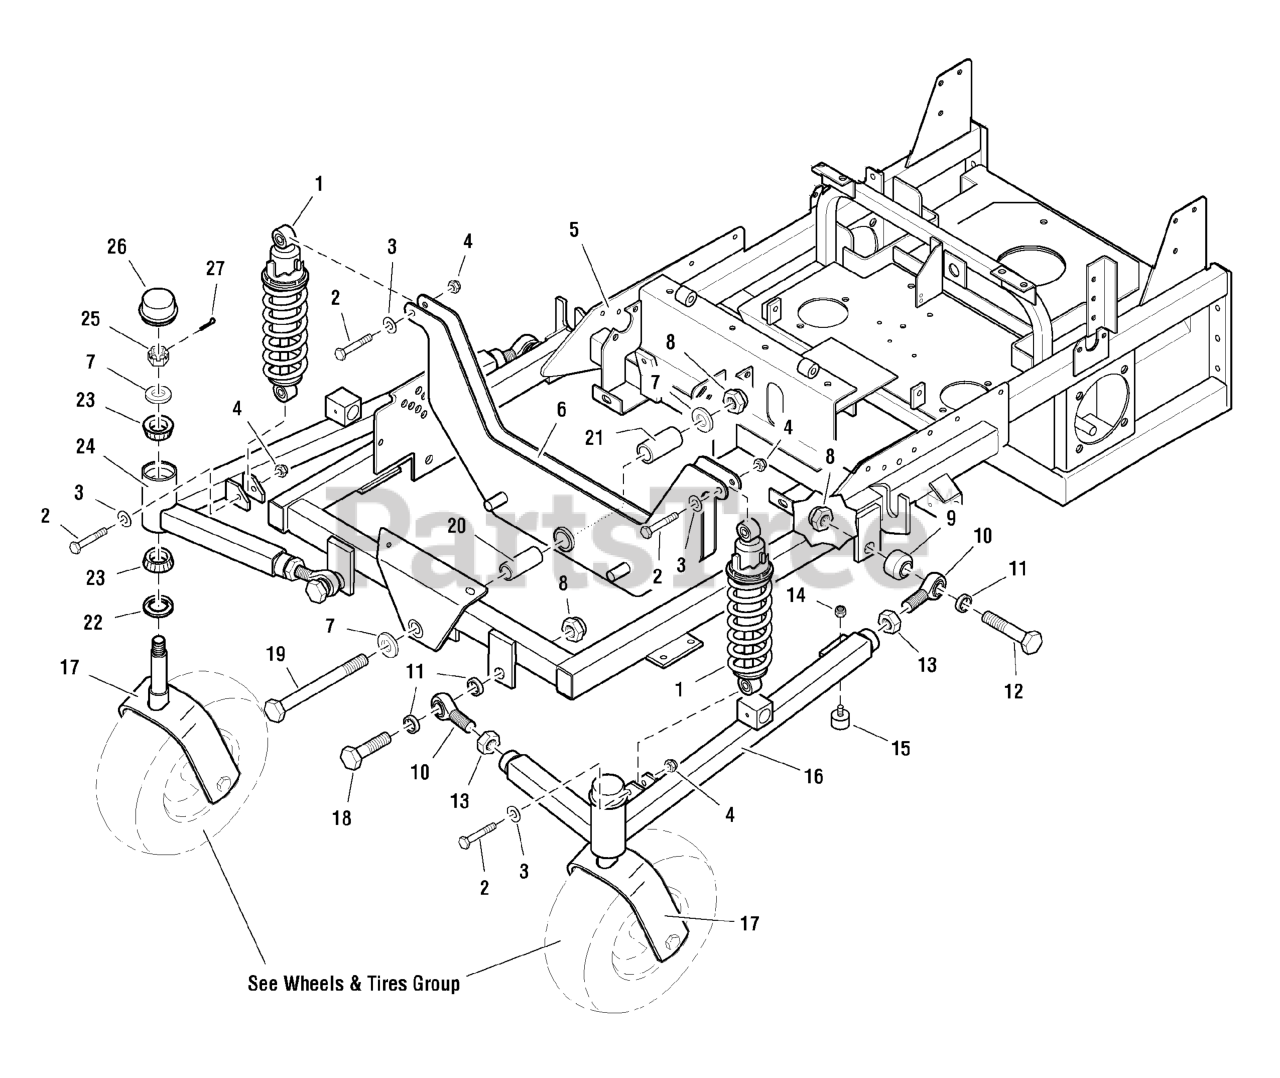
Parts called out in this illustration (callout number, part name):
1	SHOCK & SPRING ASSEMBLY
2	BOLT, 3/8-16 X 2, GD5, CZ
3	WASHER, 3/8 SAE
4	NUT, 3/8-16 HEX NYLON LOCK
5	MAIN FRAME
6	UPPER SHOCK MOUNT
7	WASHER, 3/4 SAE
8	NUT, 3/4-16 Hex Nylon Lock
9	SPACER, .75 x 1.50 x 1.00
10	BALL JOINT, 3/4-16 Male
11	SPACER, .76 x 1.00 x .25
12	BOLT, 3/4-16 x 4
13	NUT, 3/4-16 Hex Jam
14	NUT, 1/4-20 HEX NYLON LOCK
15	RUBBER BUMPER
16	SUSPENSION ARM ASSEMBLY - LH, Complete
17	CASTER YOKE
18	BOLT, 3/4-16 x 3
19	BOLT, 3/4-16 x 6
20	SPACER, .75 x 1.00 x 2.38
21	PIVOT BEARING
22	SEAL, GREASE
23	BEARING, Tapered Roller
24	SUSPENSION ARM ASSEMBLY - RH, Complete
25	NUT, 3/4-16 Hex Slotted
26	CAP
27	PIN, COTTER, 1/8 X 1-1/4
